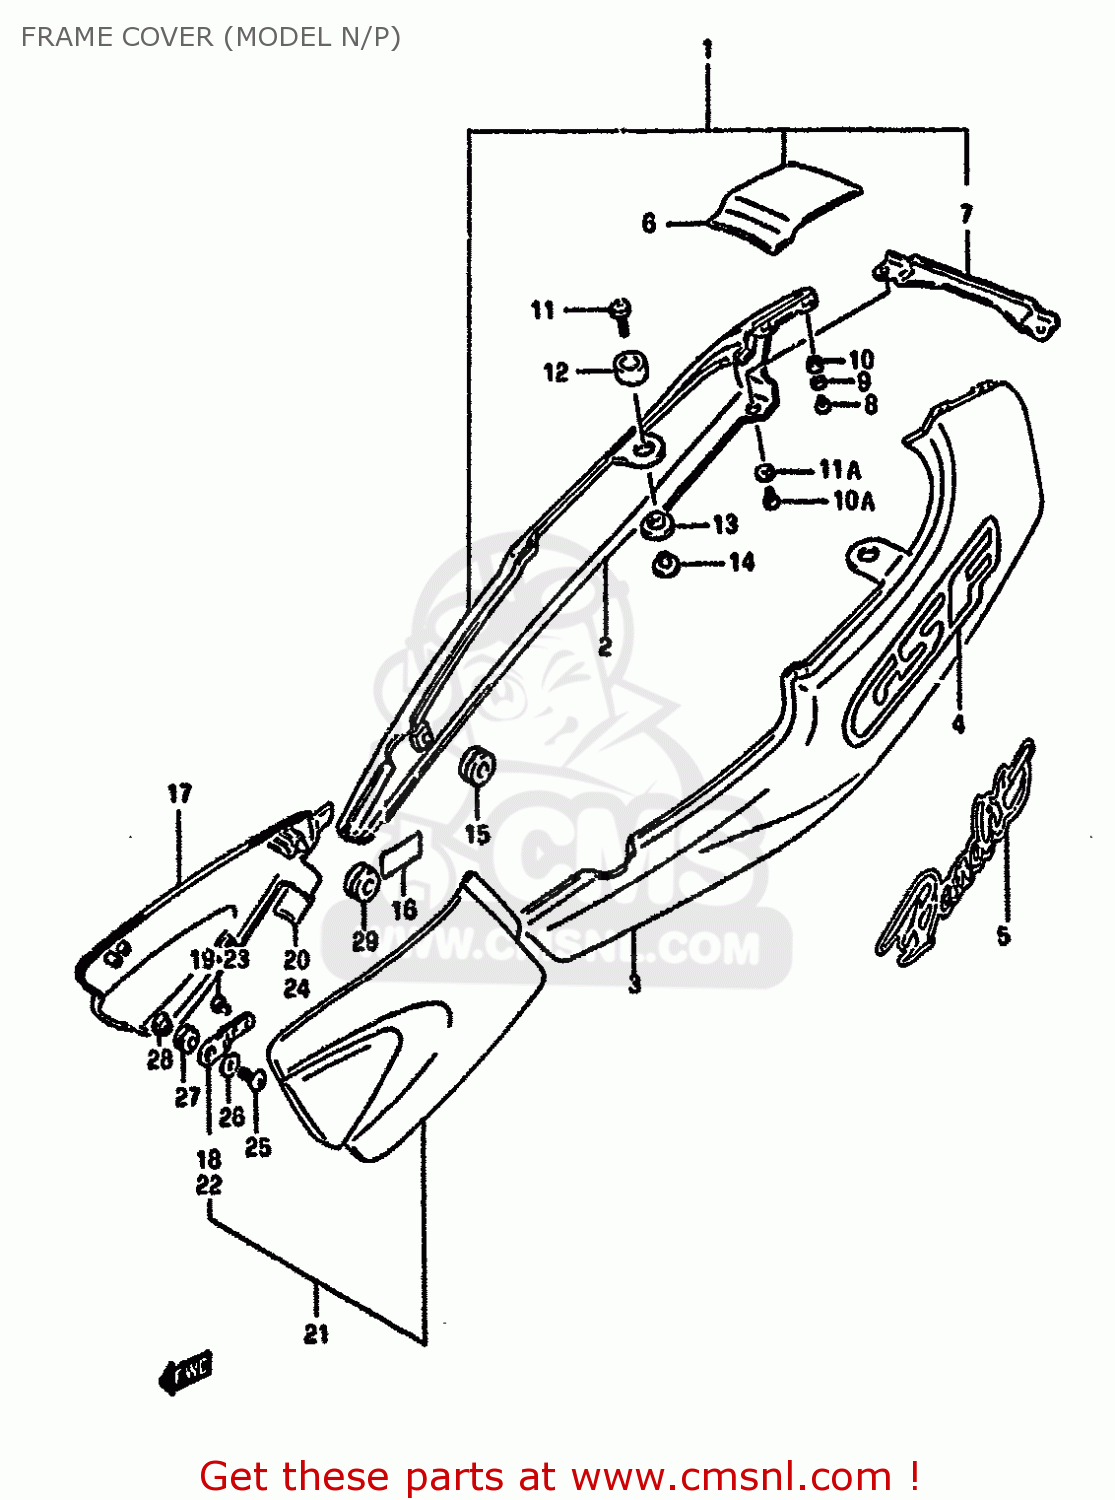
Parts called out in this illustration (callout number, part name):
1	COVER ASSY,FRAME (RED)
2	COVER,FRAME,R(RED)
3	COVER,FRAME,L(RED)
4	EMBLEM
5	EMBLEM,FRAME COVER
6	COVER,FRAME RR
7	COVER,FRAME RR LWR
8	SCREW
9	WASHER
10	SPACER,RR COVER
10A	WASHER
11	SCREW(6X25)
11A	SCREW (5X20)
12	CUSHION,TAIL COVER UPR
13	CUSHION,TAIL COVER LWR
14	SPACER,SEAT TAIL COVER
15	CUSHION
16	PROTECTOR,FRAME COVER
17	COVER COMP,AIR CLEANER,RIGHT
18	PLATE,AIR CLEANER COVER
19	SCREW
20	CUSHION
21	COVER,AIR CLEANER,L
22	PLATE,AIR CLEANER COVER
23	SCREW
24	CUSHION
25	SCREW(6X20)
26	WASHER(6.5X18X1)
27	CUSHION
28	WASHER
29	CUSHION
